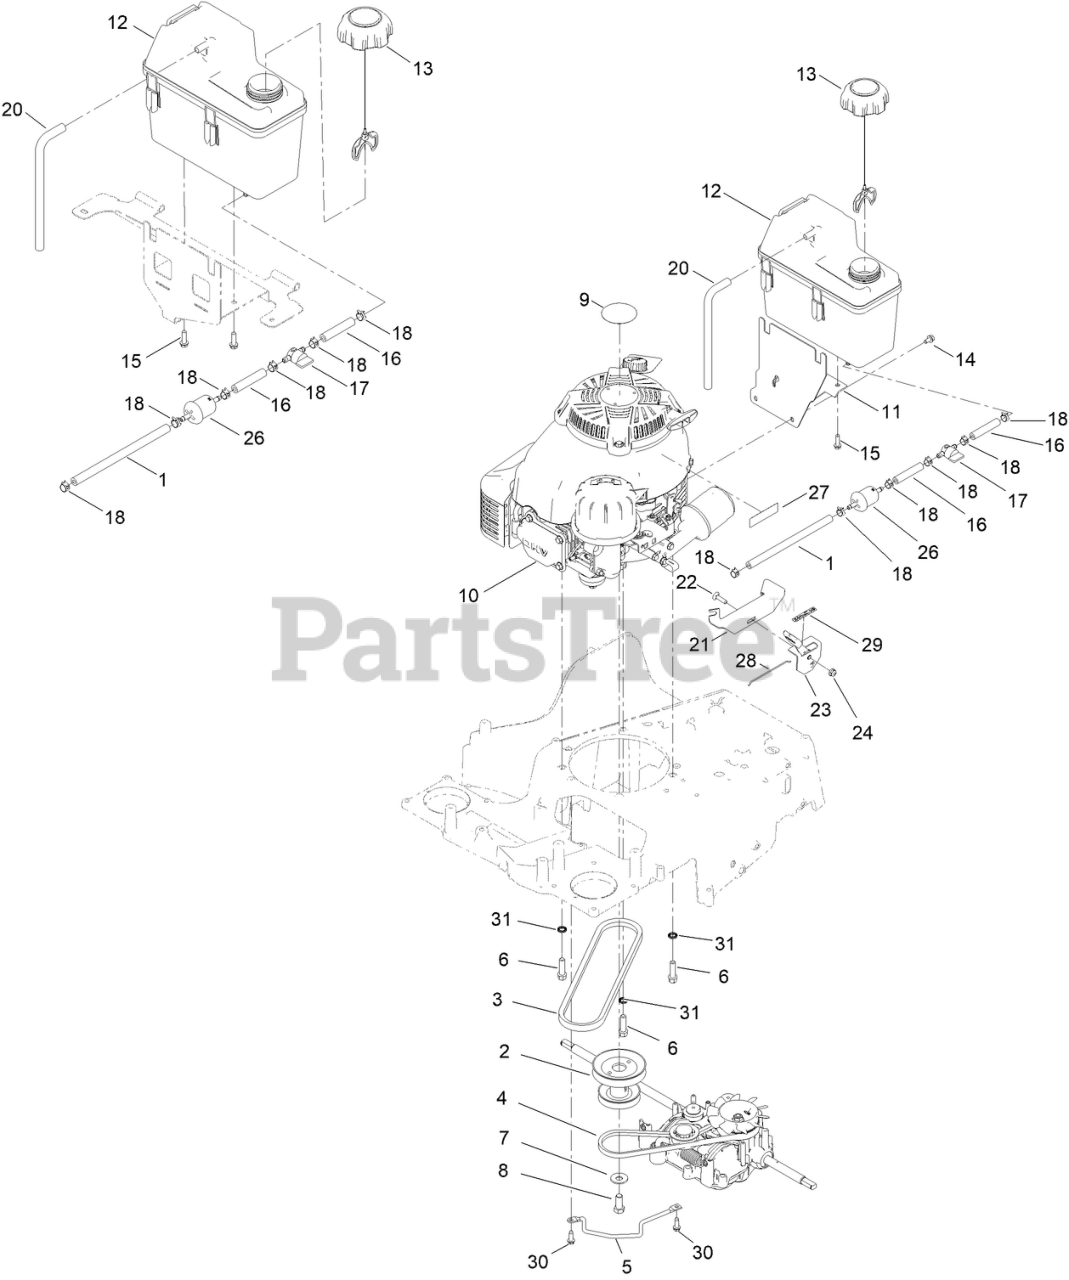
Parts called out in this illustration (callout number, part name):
1	HOSE-FUEL
2	PULLEY-ENGINE
3	V-BELT
4	BELT-V
5	ROD-GUIDE, BELT
6	SCREW-TAPTITE
7	WASHER-BELLEVILLE
8	SCREW-HH
11	MOUNT-TANK
12	TANK-FUEL
13	CAP-FUEL
14	SCREW-HWH
15	SCREW-HWH
16	HOSE-FUEL
17	VALVE-FUEL
18	CLAMP-HOSE
20	HOSE-VENT, CANISTER
21	BRACKET-MOUNT, THROTTLE
22	SCREW-CARR
23	CONTROL-THROTTLE
24	NUT-HF
26	FILTER-FUEL
27	DECAL-WARNING, ENGINE
28	WIRE-CONTROL
29	DECAL-THROTTLE, CHOKE
30	SCREW-HWHTF
31	WASHER-LOCK
